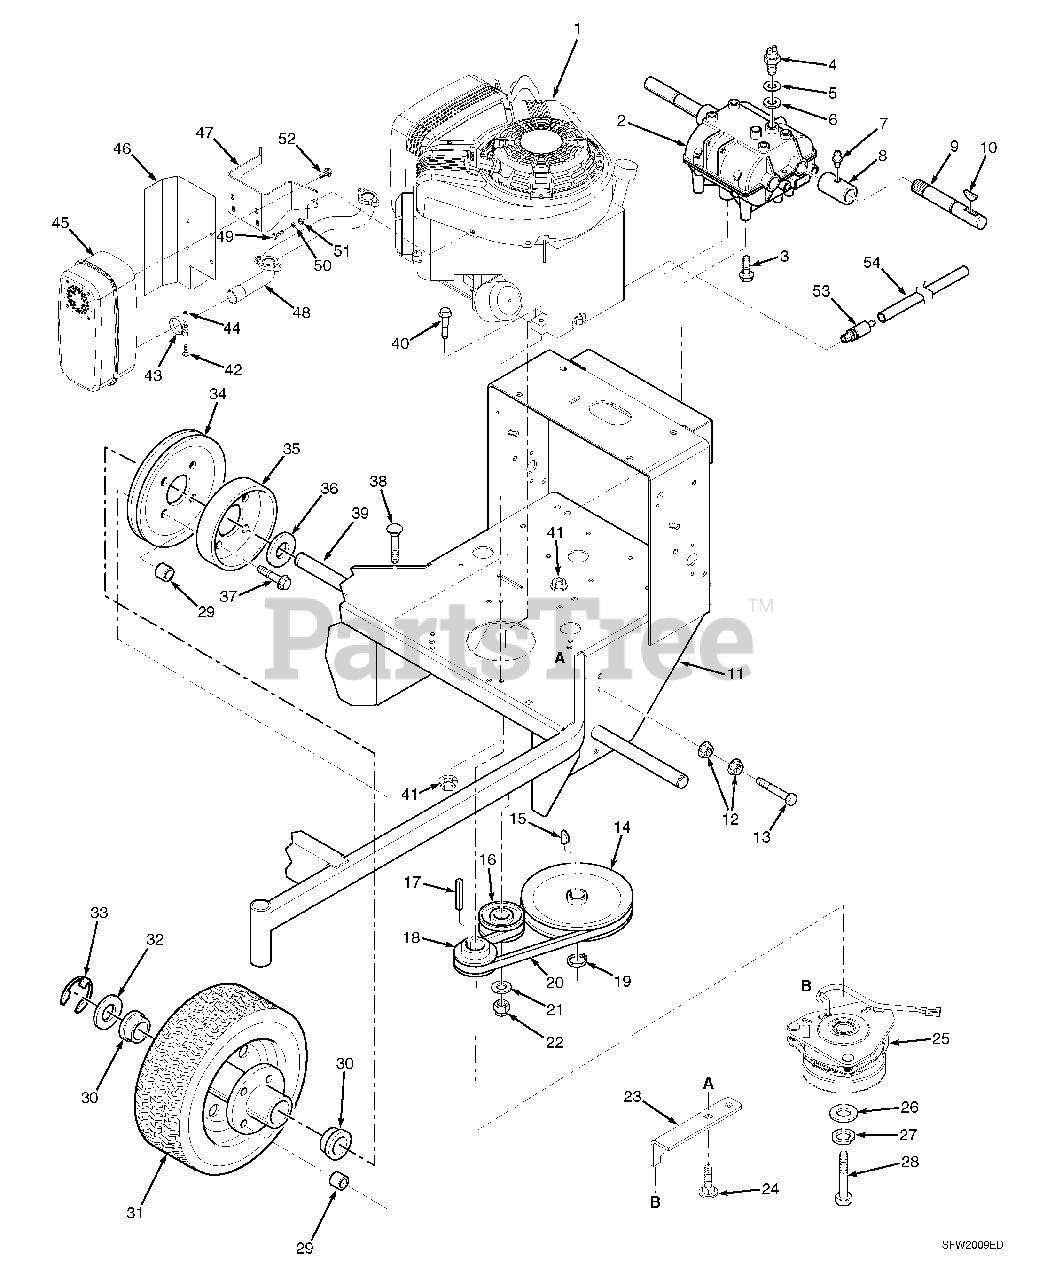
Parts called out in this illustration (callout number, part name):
1	Engine, 16HP Briggs & Stratton
2	Transmission, 4-Speed
3	Bolt, Serrated Flange 5/16-18 x 3/4"
4	Switch, Neutral Interlock
5	Fiber Washer, Thin
6	Fiber Washer, Thick
7	Grease Fitting, Straight 1/4-28
8	Coupler, Jackshaft
9	Jackshaft
10	Key, Hi-Pro #9
11	Frame Weldment w/Decals
12	Nut, Serrated Flange 3/8-16
13	Bolt, Hex Head 3/8-16 x 1"
14	Pulley, Transmission Input
15	Key, Woodruff #9
16	Pulley, Idler 3-1/2"
17	Key, 1/4 x 1/4 x 3/4"
18	Pulley, 2-3/4 OD x 1" Bore
19	Retaining Ring, .625 Ext.
20	Belt, Transmission
21	Flatwasher, 3/8-.391 x .935 x .105 HD
22	Nut, Elastic Stop 3/8-16
23	Bracket, Anti-Rotation
24	Bolt, Carriage 5/16-18 x 3/4"
25	Clutch, Ogura GT1A
26	Flatwasher, 7/16-.469 x 1-3/4 x .25
27	Lockwasher, 7/16" Spring
28	Bolt, Hex Head 7/16-20 x 2-3/4" w/ Patch
29	Spacer, Wheel Assembly
30	Bearing
31	Wheel Assembly
32	Flatwasher, 1-1.062 x 1-1/2 x .0478
33	Retaining Ring, 1" Ext. "E"
34	Pulley, Wheel
35	Brake Drum
36	Flatwasher, 1-1.063 x 1-1/2 x .105
37	Bolt, Hex Head 5/16-18 x 1-1/2" SF
38	Bolt, Carriage 3/8-16 x 2"
39	Wheel Axle
40	Bolt, Serrated Flange 5/16-18 x 1-1/2"
41	Nut, Serrated Flange 5/16-18
42	Bolt, Carriage 5/16-18 x 1-1/4"
43	Muffler Clamp
44	Nut, 5/16-18 UNC
45	Muffler, 16HP Briggs & Stratton
46	Heatshield, 16HP Briggs & Stratton
47	Mounting Bracket, Muffler 16HP Briggs & Stratton
48	Exhaust Manifold, 16HP Briggs & Stratton
49	Bolt, M6-1 x 16mm
50	Lockwasher, 1/4" Spring
51	Flatwasher, 1/4-.312 x .750 x .065
52	Capscrew, 1/4-20 x 3/4" Shakeproof
53	Oil Drain, SFW
54	Tubing, Oil Drain 1/2 x 14"
